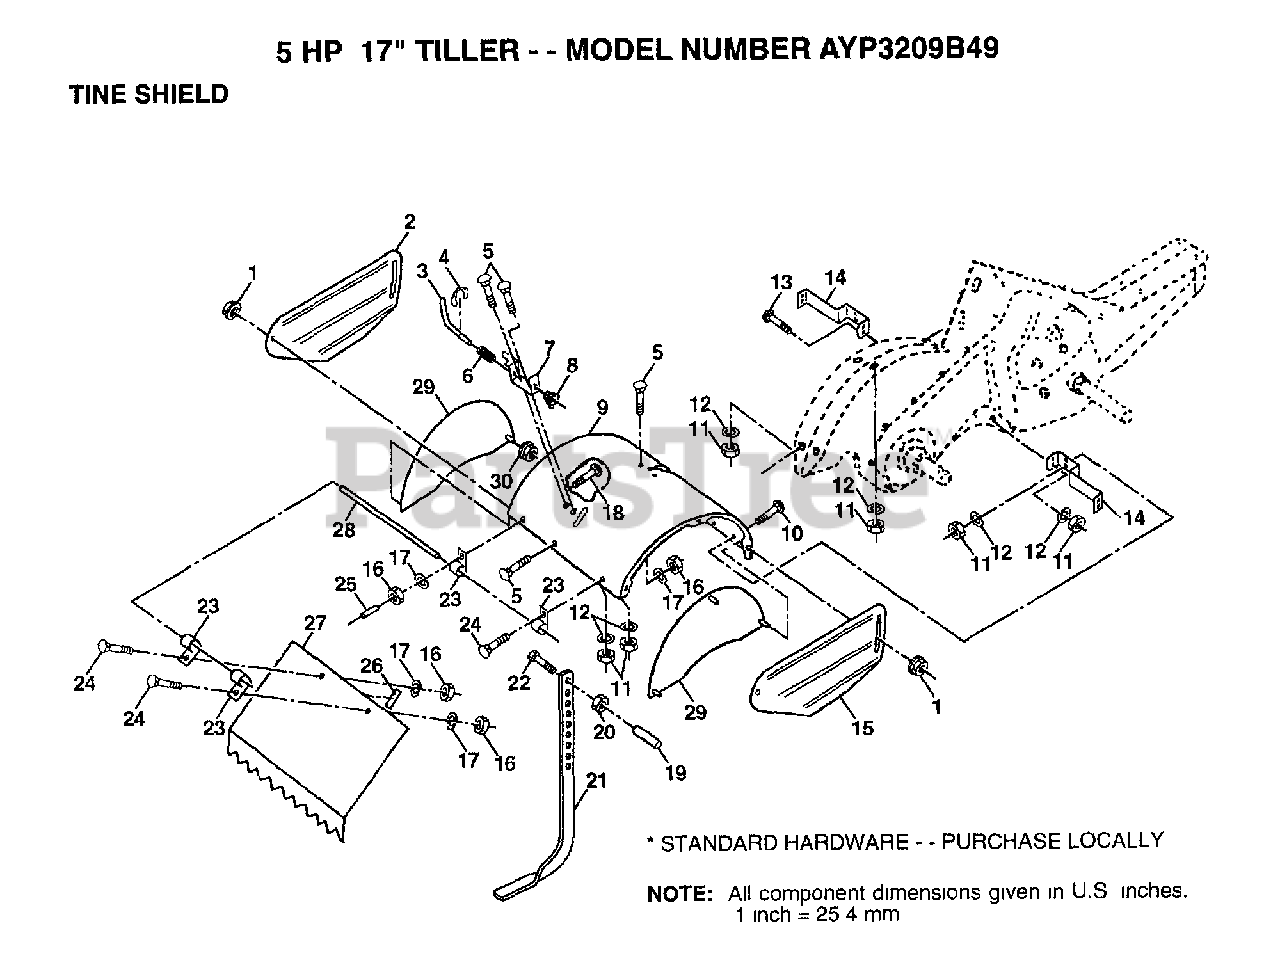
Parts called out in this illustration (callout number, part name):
1	NUT
2	SHIELD.SD.OUT.LH
3	STAKE PIN TI
4	KLIP RING TI
5	BOLT
6	SPRING TI
7	LATCH BRACKET TI
8	SPRING CRT
9	TINE SHIELD
10	BOLT
12	LOCKWASHER
13	BOLT
14	"BRACKET,SHIELD"
15	SHIELD.SD.OUT.RH
17	LOCKWASHER
18	BOLT
19	GRIP CRT
20	NUT.HEX.3/8-16UNC
21	STAKE DEPTH 16
22	BOLT
23	HINGE CRT
24	BOLT
25	VINYL CAP TI
26	PAD IDLER TI
27	LEVELING SHIELD
28	PIN HINGE
29	SIDE SHIELD
30	LOCKNUT TI
